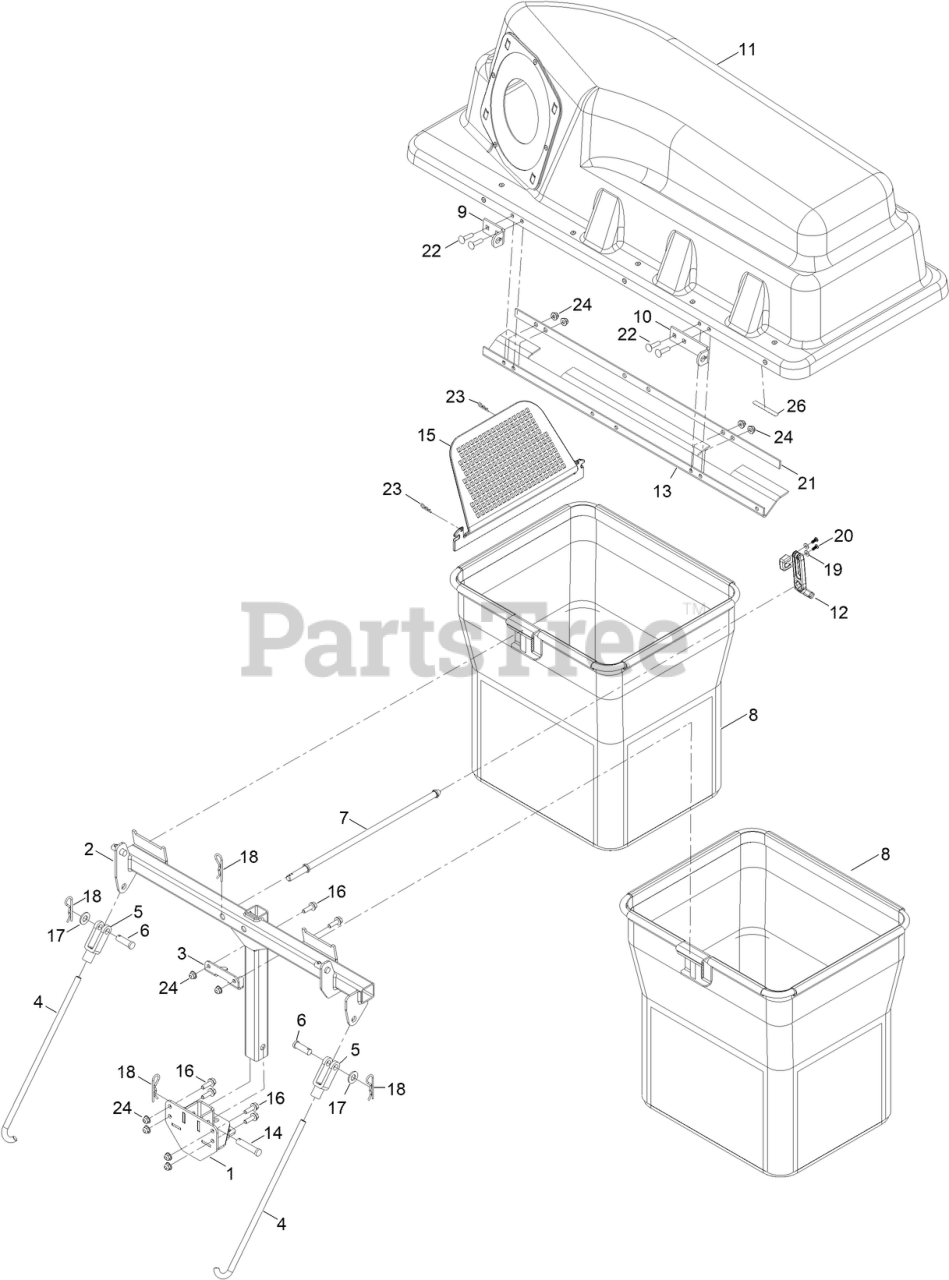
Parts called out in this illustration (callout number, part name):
1	MOUNT-BAGGER [BLACK]
2	FRAME-BAGGER [BLACK]
3	PLATE-BAGGER STABILIZER
4	ROD-BAGGER SUPPORT
5	CLEVIS
6	PIN-CLEVIS
7	ROD-HOOD, DOWN (HOLD)
8	BAG ASM
9	BRACKET-HOPPER PIVOT
10	BRACKET-HOPPER PIVOT
11	BAGGER HOOD ASM
12	LATCH-RUBBER
14	PIN-CLEVIS
15	SCREEN-BAGGER
16	SCREW-HHF
17	WASHER-FLAT
18	PIN-HAIR
19	WASHER-PLAIN
20	SCREW-PPH
21	PLATE-BACKING
22	BOLT-CARRIAGE
23	PIN-HAIR
24	NUT-HF
26	DECAL-WARNING
